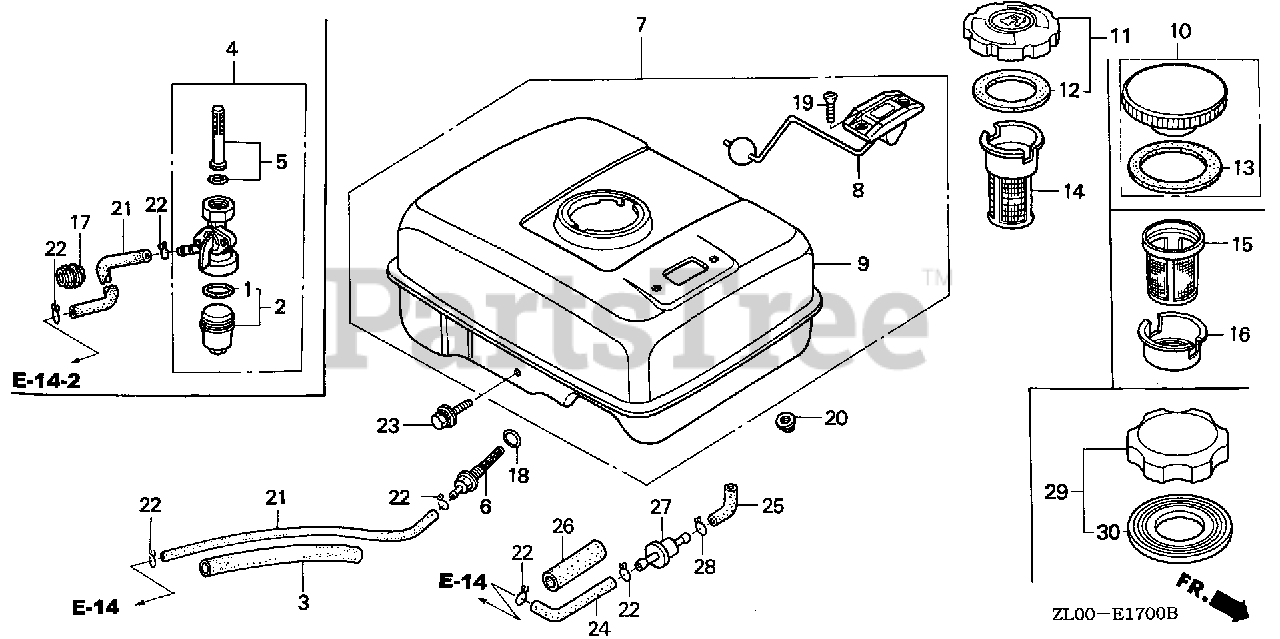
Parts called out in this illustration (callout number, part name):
3	RUBBER, SUPPORTER (107MM)
6	JOINT, FUEL TANK
9	TANK, FUEL *NH31* (MCKINLEY WHITE)
9	TANK, FUEL *NH1* (BLACK)
11	CAP, FUEL FILLER (BLACK)
12	GASKET, FUEL FILLER CAP (39X58X3)
18	O-RING (14MM) (ARAI)
18	O-RING (14MM) (NOK)
20	NUT, FLANGE (6MM)
21	BULK HOSE, FUEL (4.5X3000) (4.5X140)
22	CLIP, TUBE (B8)
23	BOLT, FLANGE (6X34)
29	CAP, FUEL FILLER (CHROME PLATED)
30	GASKET, FUEL FILLER CAP (39X62X3) (TOUYOUSYA)
